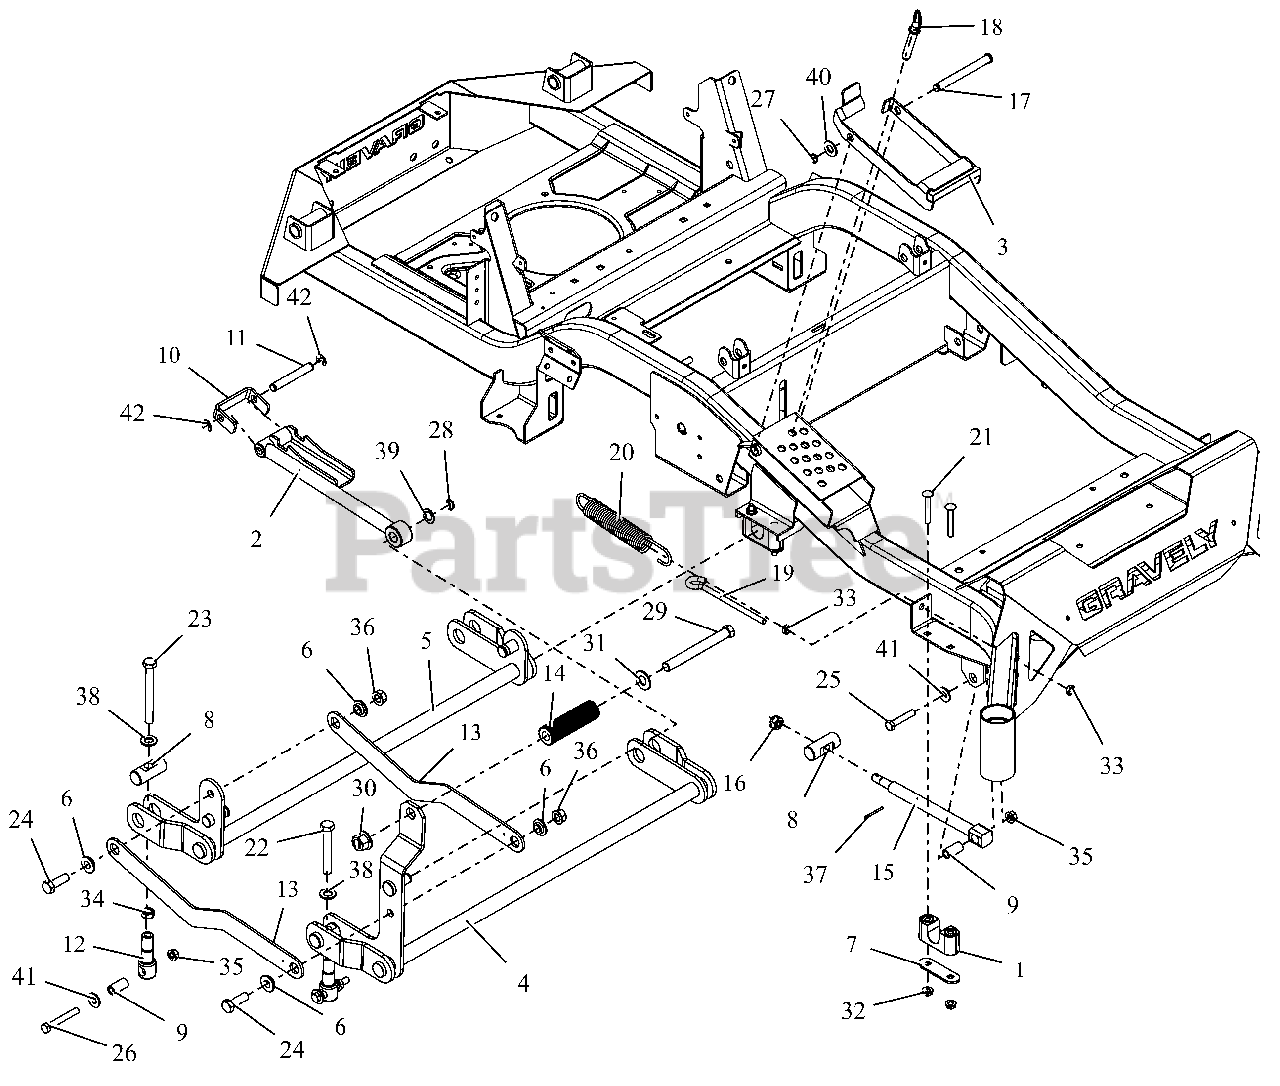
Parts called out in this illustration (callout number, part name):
1	ASM-BUSHING, DECK LIFT
2	WLDMT, HOC ARM
3	BRKT, HOC TRANSFER LOCK
4	WLDMT, FRONT DECK LIFT PIVOT
5	WLDMT, REAR DECK LIFT PIVOT
6	BSHG-FLG .515X.750X.310X1.120
7	PLATE, BEARING SUPPORT
8	PIN, DECK LIFT
9	SPACER, DECK LEVELING
10	BRKT, HOC LINE
11	ROD, HOC PIVOT
12	LINK, DECK LIFT FORMED
13	LINK, DECK LIFT
14	ROD, FOOT PEDAL (BLACK)
15	DRAG,LINK-HD
16	NUT-SL .50-13
17	PIN-CLEV .50X4.75X4.55
18	PIN, .50 X 2.20 USABLE LG BALL
19	BOLT,.38-16 X 5.25-.62 DIA EYE
20	SG-TENS .162X1.25X8.25 WLD 25
21	BLT-RDHDSQSHNK .31-18X2.25 YWZ
22	BLT-HEX .50-13X3.50 GR5 FTH
23	@BLT-HEX .5-13-4.5GR8 FULL THD
24	@BLT-HEX .50-13X1.50 GR5 YWZC
25	@BLT-HEX .38-16X2.00 GR5 YWZC
26	BLT-HEX .38-16X2.75 GR8 YWZC
27	RG-RTNG-EXT .500X.050 (SNAP)
28	RG-RTNG-EXT .625X.050
29	BLT, HEX .62-11X5.50 G5 FBP
30	NUT,FLG-TOP LK .625-11 FBP
31	WSHRFLT 5/8SAE CARBHARD FBP
32	@NUT-LK-CTR-FLG .31-18 YZ GR F
33	NUT-HEX-JAM .375-16 YWZC
34	NUT-JAM .50-13 YWZC
35	@NUT-LK-TOP-FLG .38-16 YWZC
36	@NUT-LK-TOP-FLG .50-13 YWZC
37	@PIN-CTR .12X1.25 EXTPRSQCT YZ
38	FLATWASHER 1/2 SAE HARD 15906
39	WSHR-FL-STL .630X1.005X.062 YZ
40	@WSHR-FL-STL.531X1.06X.095YWZC
41	@WSHR-FL-STL.438X1.00X.083 YWZ
42	RG-RTNG-EXT .500X.042 (E)
